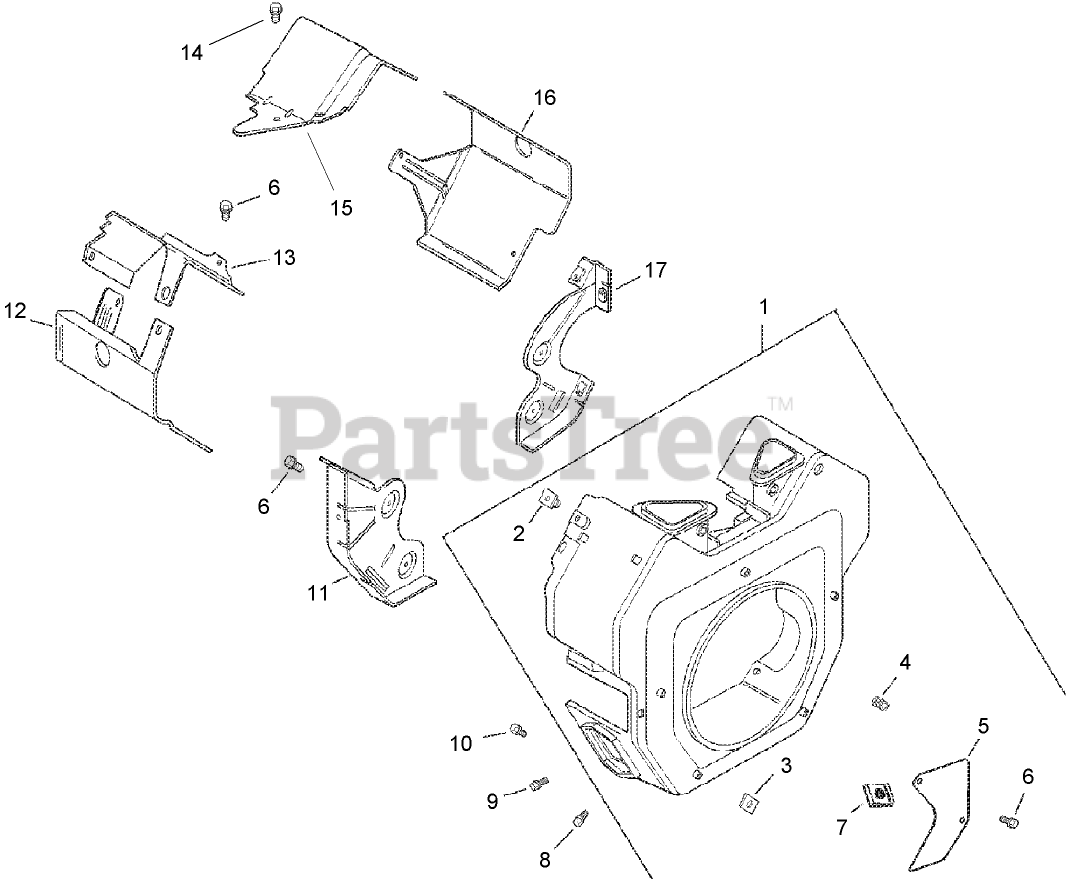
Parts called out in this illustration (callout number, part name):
1	Housing-Blower (Incl. Ref. #2-7)
2	Nut-Plastic
3	NUT-PLASTIC
4	Screw-Set (10-24X.25)
5	Access Cover Kit (Incl. Ref. #6-7)
6	SCREW-FLANGE, THREAD FORMING (M6X1.0X16)
7	Clip-Mounting
8	Screw-Hex Flange, Heavy (M5x0.8x16)
9	SCREW-FLANGE, THREAD FORMING (M5X0.8X16)
10	SCREW-FLANGE, THREAD FORMING (M5X.8X20)
11	Plate-Backing, No.2 Side
12	Baffle-Cylinder Barrel, No.2 Side
13	Baffle-Valley, No.2 Side
14	SCREW-HHFTF (M5X.80X10)
15	Baffle-valley, No. 1 side
16	Baffle-Cylinder Barrel, No.1 Side
17	Plate-Backing, No.1 Side
